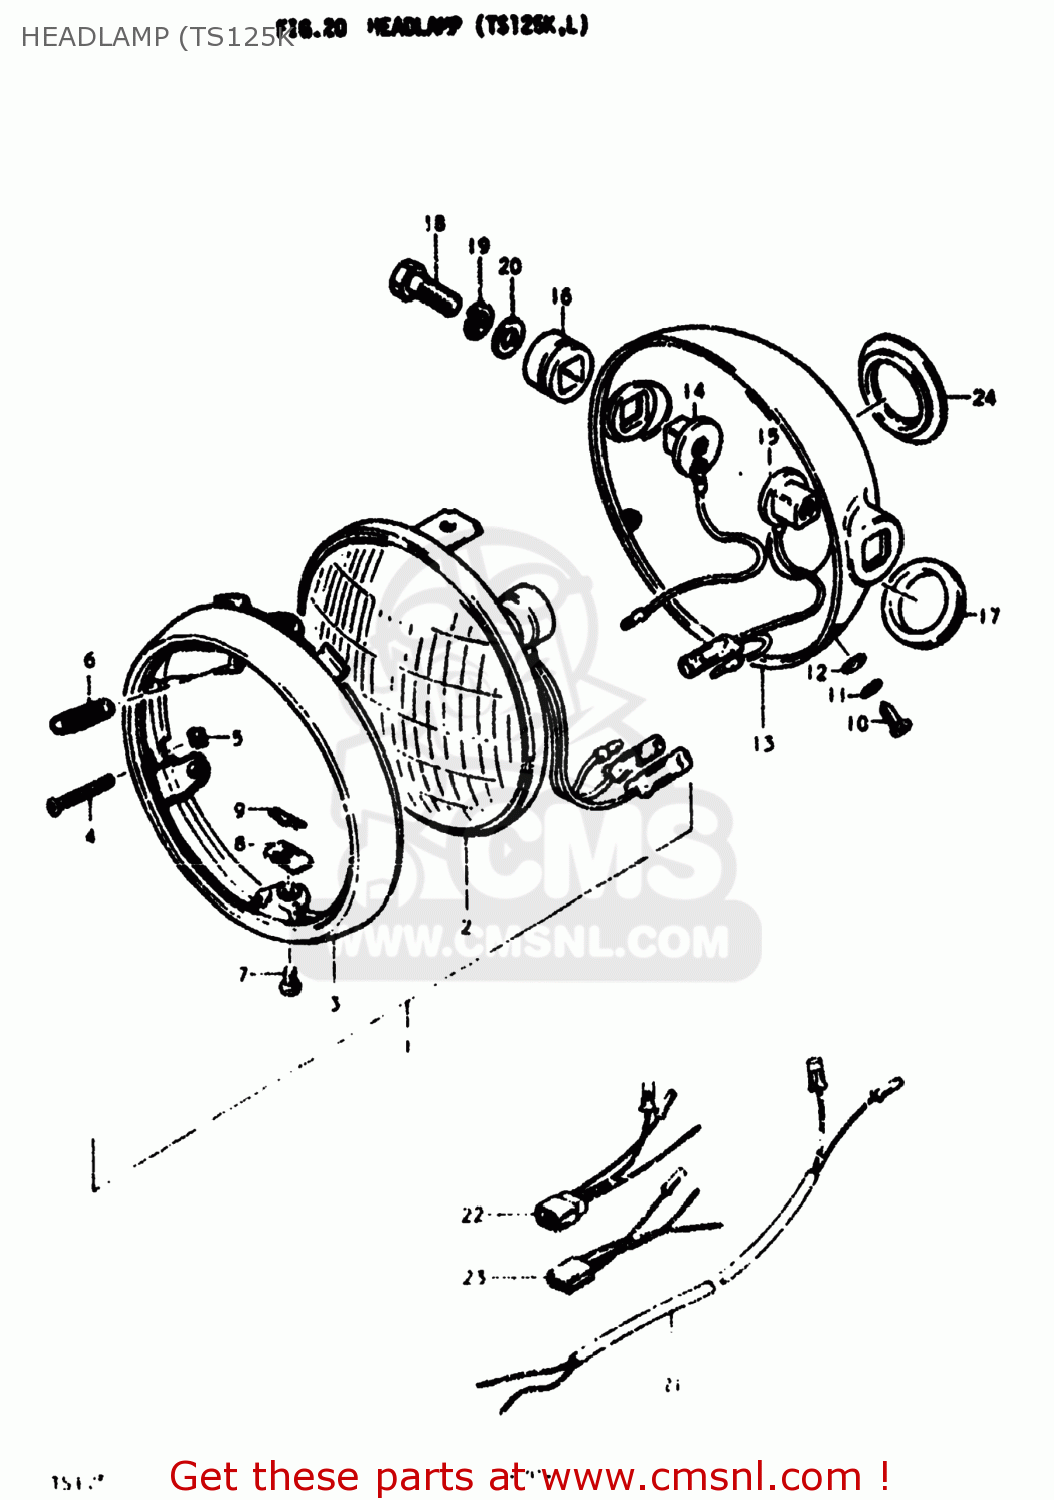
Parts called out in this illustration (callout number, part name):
1	HEADLAMP ASSEMBLY
2	LAMP UNIT
3	RIM,HEADLAMP
4	SCREW,HEADLAMP ADJUST
5	NUT,HEADLAMP ADJUSTER
6	SPRING,HEADLAMP ADJUST
7	SCREW,LENS
8	NUT,ADJUSTING
9	CUSHION,HEADLAMP
10	SCREW
11	LOCK WASHER
12	WASHER
13	HOUSING,HEADLAMP
14	9100
15	SPACER,HEADLAMP HOUSING
16	CUSHION,HEADLAMP HOUSING
17	GROMMET,HEADLAMP HOUSING
18	BOLT
19	LOCK WASHER
20	WASHER
21	WIRE
22	WIRE,HEADLAMP GROUND
23	WIRE
24	CAP
